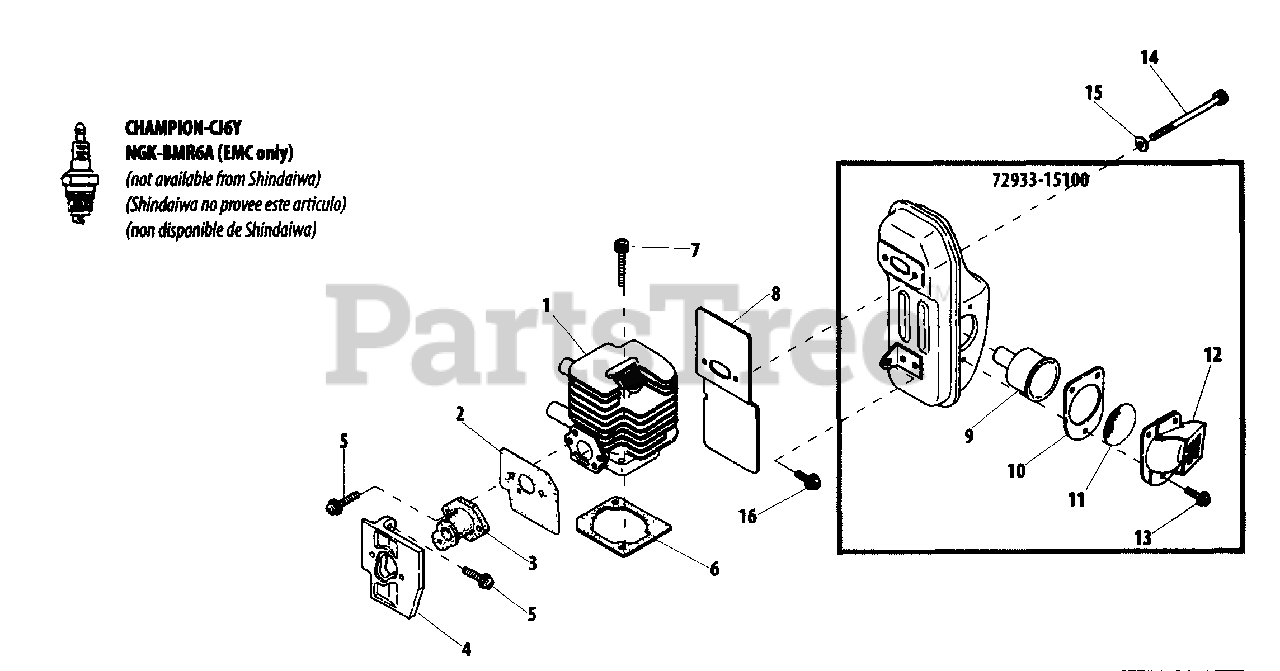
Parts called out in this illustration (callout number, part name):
1	CYLINDER
2	GASKET
3	BOOT
4	BRACKET
5	SCREW - 5X16
6	GASKET, CYLINDER
7	SCREW - 5X20
8	GASKET, EXHAUST
9	CHAMBER
10	GASKET
11	SCREEN, SPARK ARRESTOR
12	GUIDE, EXHAUST
13	SCREW - 4X10
14	SCREW - 5X55
15	WASHER - 5
16	SCREW - 5X16
